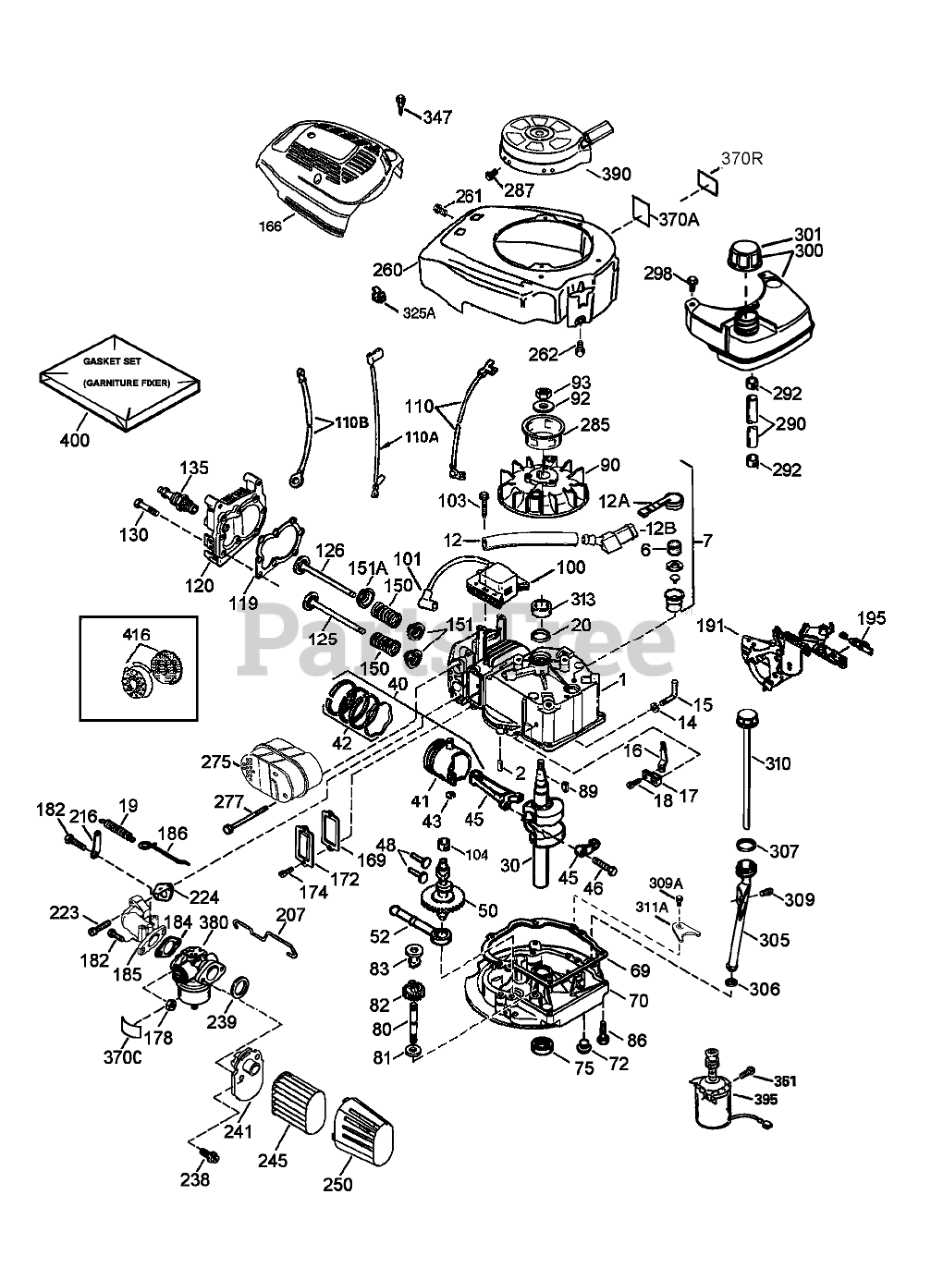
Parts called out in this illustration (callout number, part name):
1	Cylinder (Incl. Ref. #2, 20 and 150)
2	Pin-Dowel
6	Element-Breather
7	Breather ASM (Incl. Ref. #6 and 12A)
12	Tube-Breather
12A	Breather Cover and Tube ASM (Incl. Ref. #12B)
12B	Elbow-Tube, Breather
14	Washer-Flat
15	Rod-Governor (Incl. Ref. #14)
16	Lever-Governor
17	Clamp-Lever, Governor
18	Screw (T-15, 8-32 x 19/64)
19	Spring-Extension
20	Seal-Oil
30	Crankshaft
40	Piston, Pin and Ring Set (Std.)
41	Piston and Pin ASM (Std.) (Incl. Ref. #43)
42	Ring Set (STD)
43	Ring-Retaining, Piston Pin
45	Connecting Rod ASM (Incl. Ref. #46)
46	Bolt-Rod, Connecting
48	Lifter-Valve
50	Camshaft (Exhaust MCR) (Incl. Ref. #104)
52	Oil Pump ASM
69	Gasket-Flange, Mounting
70	Flange-Mounting (Incl. Ref. #72-83, 306, 309A and 311A)
72	Plug-Drain, Oil
75	Seal-Oil
80	Shaft-Governor
81	Washer-Flat
82	Governor Gear ASM (Incl. Ref. #81)
83	Spool-Governor
86	Screw (1/4-20 x 1-1/4)
89	Key-Flywheel
90	Flywheel
92	Washer-Belleville
93	Nut-Flywheel
100	Ignition-State, Solid
101	Cover-Spark Plug
103	Screw (T-15, 10-24 x 15/16)
104	Bushing-Cam
110	Wire-Ground
110A	Wire ASM
110B	Wire ASM
119	Gasket-Cylinder Head
120	Head-Cylinder
125	Valve-Exhaust (1/32" OS) (Incl. Ref. #151)
125	Valve-Exhaust (Std.) (Incl. Ref. #151)
126	Valve-Intake (Std.) (Incl. Ref. #151 and 151A)
130	Screw (5/16-18x1-1/2)
135	Spark Plug-Resistor (R J19 L M)
150	Spring-Valve
151	Cap-Valve, Spring
151A	Seal-Valve, Intake
166	Shroud-Engine
169	Gasket-Cover, Valve
172	Cover-Valve
174	Screw (10-24 x 9/16)
178	Nut and Lock Washer (1/4-28)
182	Screw (1/4-28 x 7/8)
184	Gasket
185	Pipe-Intake
186	Link-Governor
191	Bracket-Brake, S.E. (Incl. Ref. #195)
195	Terminal
207	Link-Throttle
216	Lever-Adjusting, R P M
223	Screw (1/4-20 x 1)
224	Gasket-Pipe, Intake
238	Screw (10-32 x 49/64)
239	Gasket-Cleaner, Air
241	Collar-Cleaner, Air
245	Filter-Cleaner, Air (Paper)
250	Cover-Cleaner, Air
260	Housing-Blower
261	Screw (10-24 x 9/16)
262	Screw (1/4-20 x 1/2)
275	Muffler
277	Screw (1/4-20 x 2-9/32)
285	Cup-Starter
287	Screw (8-32 x 21/64)
290	Line-Fuel (8.62)
292	Clamp-Line, Fuel
298	Screw (10-32 x 35/64)
300	Tank-Fuel (Incl. Ref. #292 and 301)
